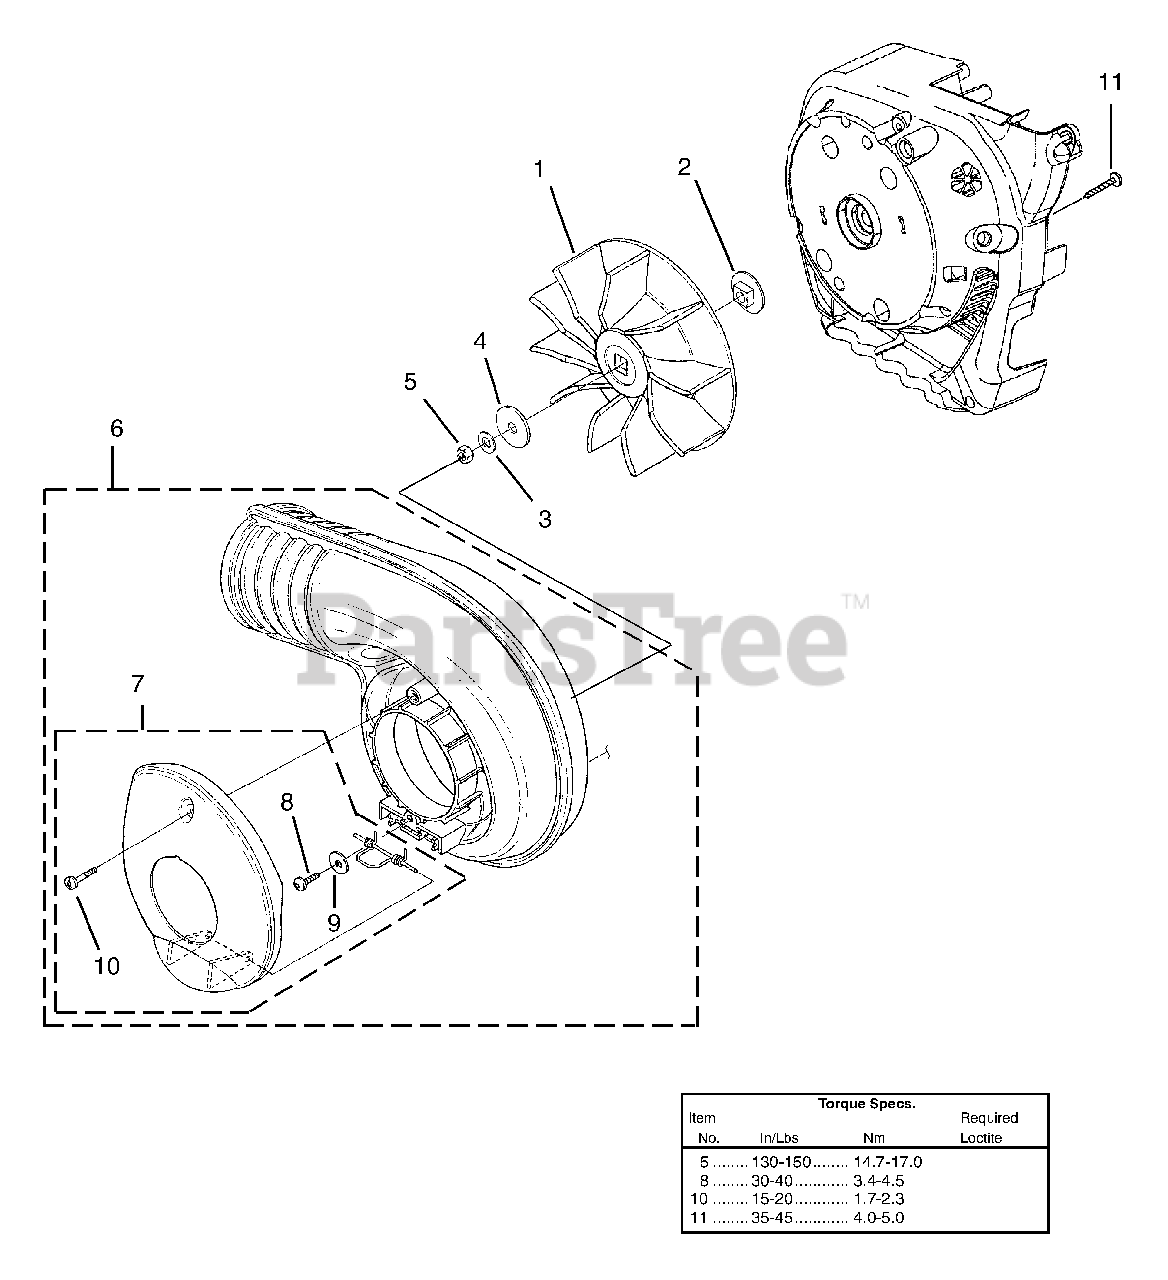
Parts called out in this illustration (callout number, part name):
2	Adapter, Fan
3	Washer, Belleville
4	Washer, Flat
5	Nut (3/8-24)
6	Volute W/Door Assembly
7	Access Door
8	Screw, Thread Forming (10-14 X 1/2 in.)
10	Screw, Machine (10-24 X 3/4 in.)
11	Screw, Plastite (10-14 X 7/8 in.)
